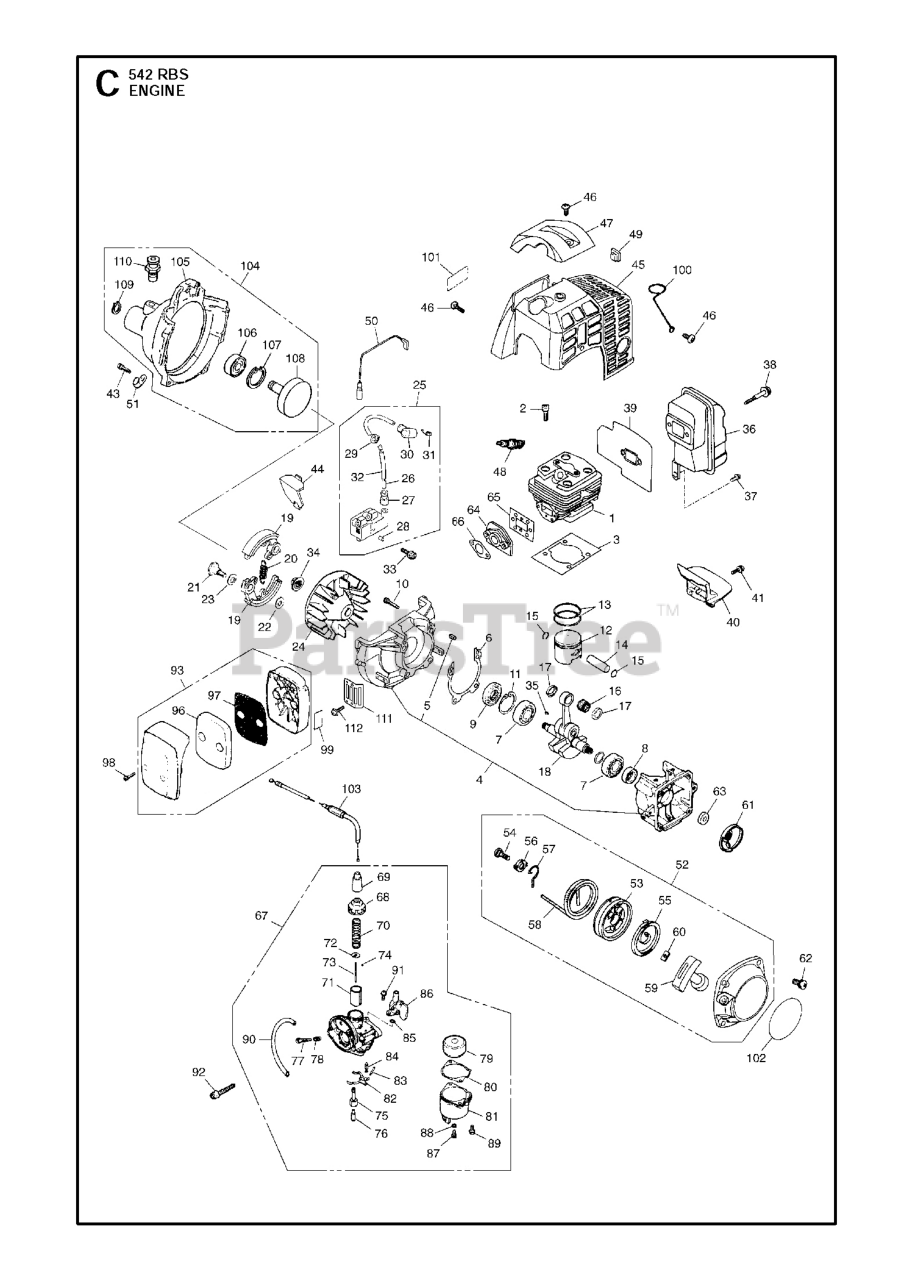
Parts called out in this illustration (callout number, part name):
13	RING, PISTON 2/PK
16	ROLLER BEARING
18	CRANKSHAFT COMPL
27	CAP
29	GROMMET
32	TUBE (RPLS 263072210)
34	NUT
40	PLATE.MUFFLER
48	SPARK PLUG RCJ6Y NLA
51	CLAMP
52	RECOIL ASSY
55	SPRING, SPIRAL
70	SPRING.THROTTLE
71	VALVE.THROTTLE
77	SCREW.ADJUST
84	VALVE.NEEDLE
